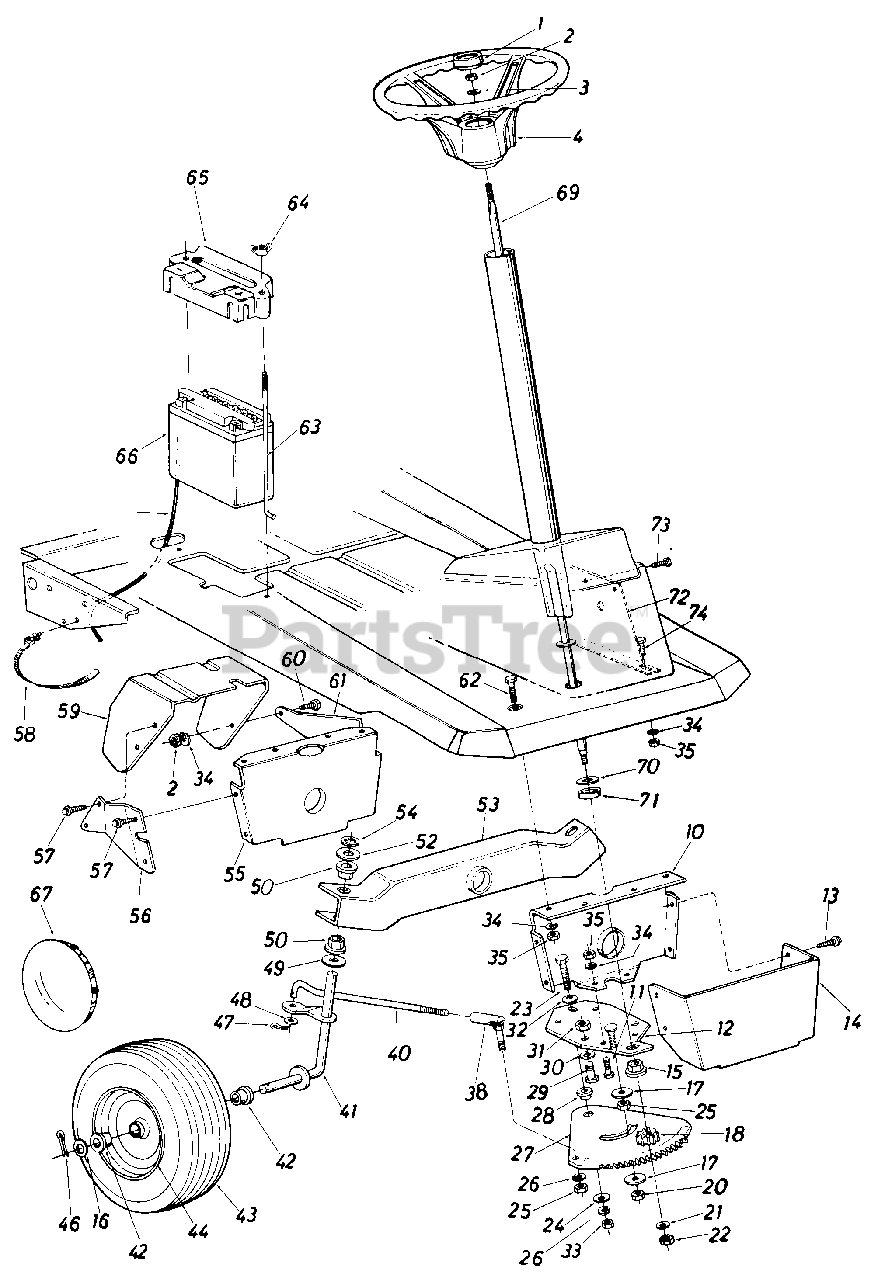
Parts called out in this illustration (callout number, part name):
1	Steering Wheel Cap
2	Hex Nut 5/16-24 Thd.
3	Bell-Wash. .345" I.D. x .88" O.D.
4	Steering Wheel Ass'y.
10	Pivot Bar Bracket
11	Hex Bolt 5/16-18 x .75" Lg.*
12	Steering Gear Support Brkt.
13	Hex Wash. Hd. AB-Tap Scr. 1/4 x.62" Lg.
16	Fl-Wash. .640" I.D. x 1.62" O.D.
17	Fl-Washer 3/8" I.D. x 1.37" O.D.
18	Steering Pinion Gear
20	Hex L-Nut 3/8-24
21	Fl-Wash. .34" I.D. x .68" O.D.
22	Hex Nut 5/16-24 Thd.*
23	Hex Bolt 3/8-24 x 1.25" Lg. (Grade 5)
24	Fl-Wash. .385" I.D. x 1.38"
25	Hex Nut 3/8-24 Thd.*
26	L-Wash. 3/8" I.D.*
27	Steering Gear Segment
28	Shoulder Spacer .622" Dia. x .218
29	Hex Bolt (Nylon) 1/2-13 x .75"
30	Fl-Wash. .530" I.D. x .930"
31	Hex Nut 1/2-13 Thd.*
32	Bell-Wash. .385" I.D. x .88"
33	Hex Nut 3/8-24 Thd.*
34	L-Wash. 5/16" I.D.*
35	Hex Nut 5/16-18 Thd.*
38	Ball Joint Ass'y. 3/8-24 Thd.
40	Steering Tie Rod
41	Front Axle Ass'y.-R.H.
42	Flange Bearing .632" I.D.
43	Front Wheel Ass'y. Comp.
44	Front Wheel Rim Only
46	Cotter Pin 1/8" Dia. x 1.25"
47	Cotter Pin 1/8" Dia. x 1.00"*
48	Fl-Wash. .385" I.D. x .87"
49	Fl-Wash. .635" I.D. x 1.12"
50	Hex Flange Bearing
52	Fl-Wash. .635" I.D. x 1.12
53	Pivot Bar Ass'y.
54	Speed Nut 5/8" I.D.
55	Pivot Bar Bracket
56	Bracket Reinforcement- 0 R. H.
57	Hex Wash. Hd. AB-Tap Scr. 1/4 x .62" Lg.
58	Cable Tie
59	Clutch-Brake Pedal Ass'y.
60	Hex Bolt 5/16-18 x .75" Lg.
61	Bracket Reinforcement-L.H.
62	Hex Bolt 5/16-18 x .75" Lg.
63	Battery Hold Down Rod
64	Wing Nut Solid 1/4-20 Thd.
65	Battery Hold Down Cover
66	12V Battery
67	Chrome Hub Cap
69	Steering Shaft Ass'y.
70	Fl-Wash. .62" I.D. x 1.25" O.D.
71	Spacer (Plastic)
74	Hex Bolt 5/16-18 x 2.00" Lg.
